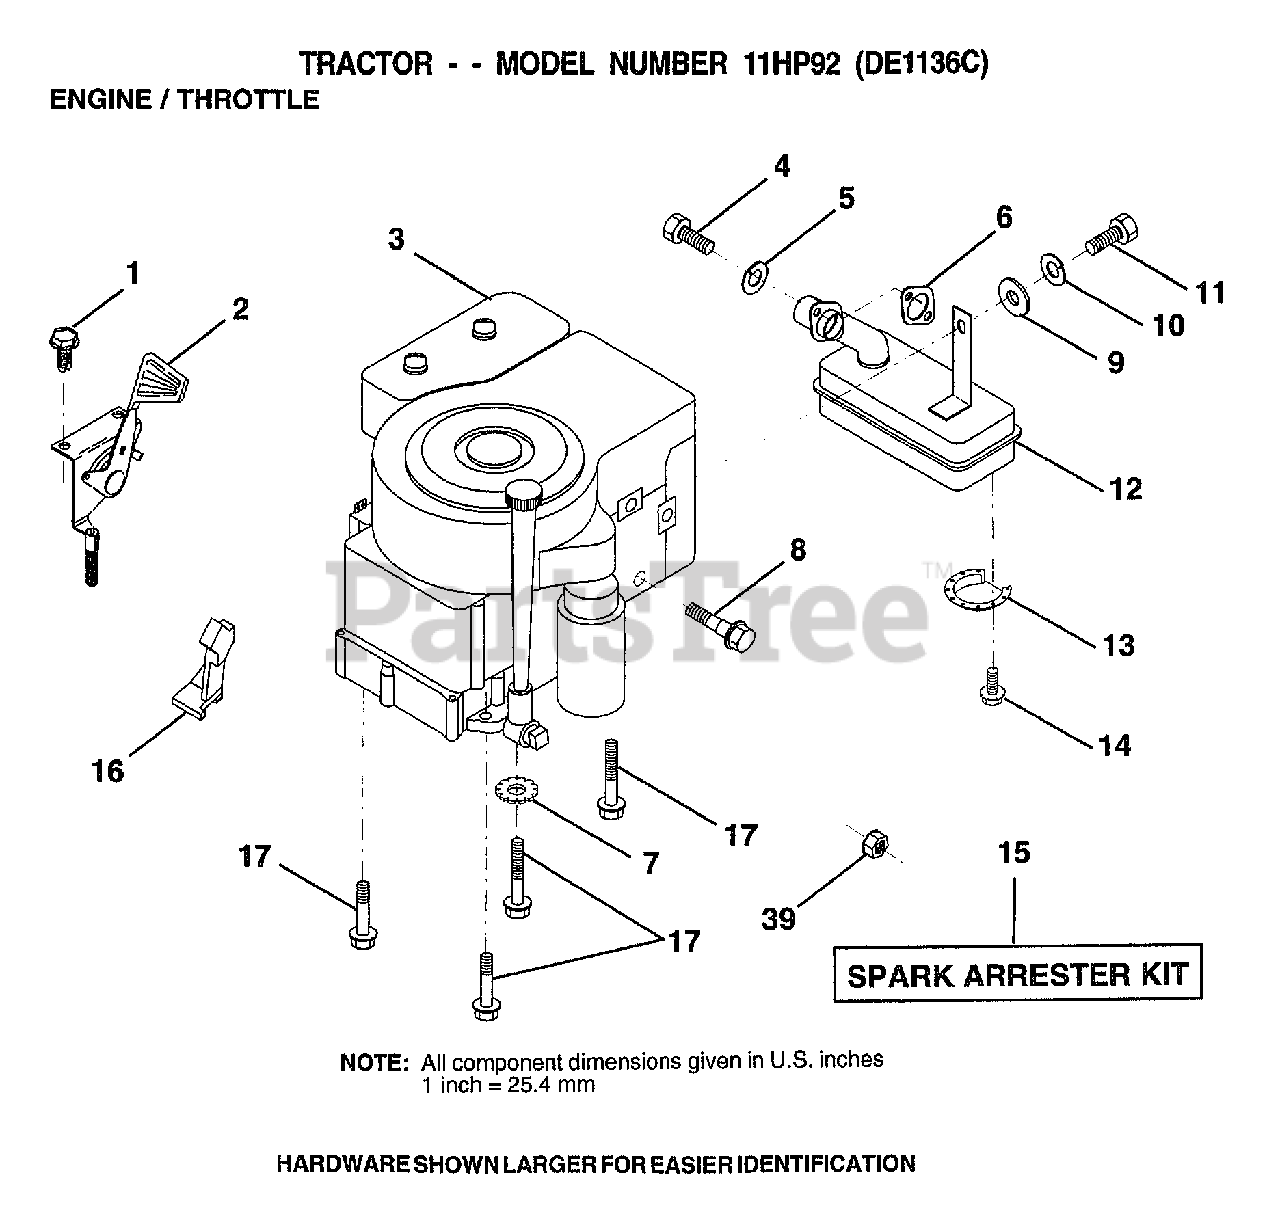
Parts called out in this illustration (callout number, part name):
1	SCREW LT
4	SCREW
5	LOCKWASHER
7	LOCKWASHER
8	BOLT T
10	LOCKWASHER
12	MUFFLER
13	DEFLECTOR.222573
16	"STOP,DASH THROTT"
17	SCREW LT
39	NUT
